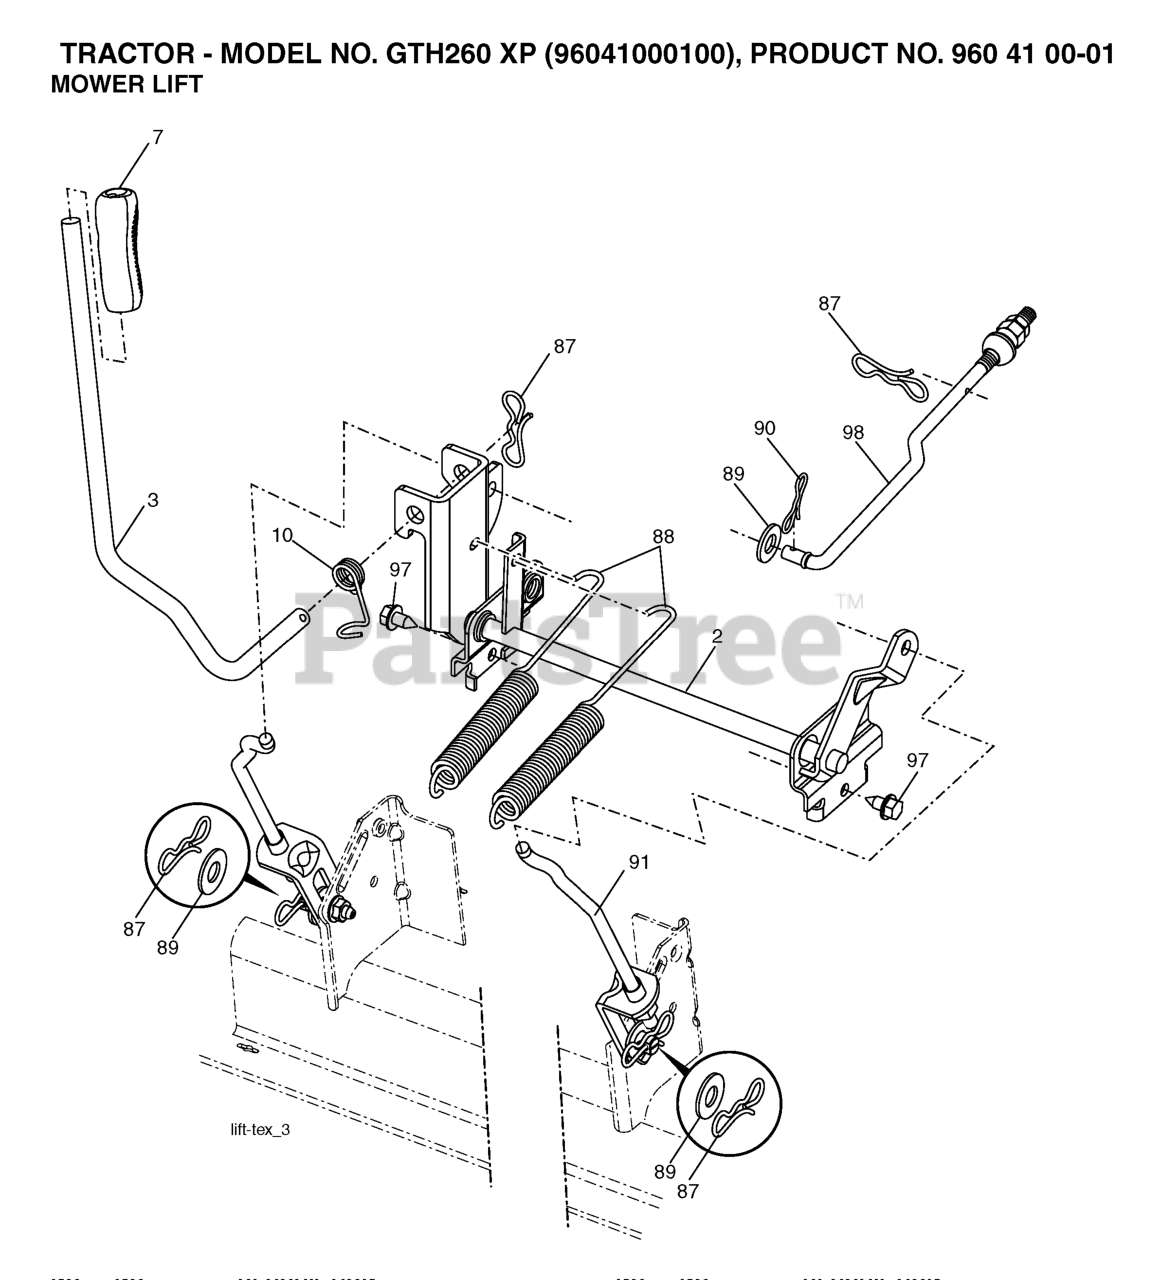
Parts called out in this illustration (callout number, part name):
2	SHAFT.ASM.LIFT.CROSS.H
3	LEVER.LIFT.HANDLE.GT
7	GRIP.LEVER.5625.ID
10	SPRING.TORSION.LIFT.HANDLE
87	PIN.COTTER.7/16.BOW TI.
88	SPRING.LIFT.ASSIST.GT2
89	WASHER.CLEAR.ZINC
90	PIN.COTTER.5/16.BOW TI
91	LINK.LIFT.ASM.REAR.GT.
97	SCREW 3/8-16X3/4
98	LINK.ASM.SUSP.FRONT.MWR.10.5
